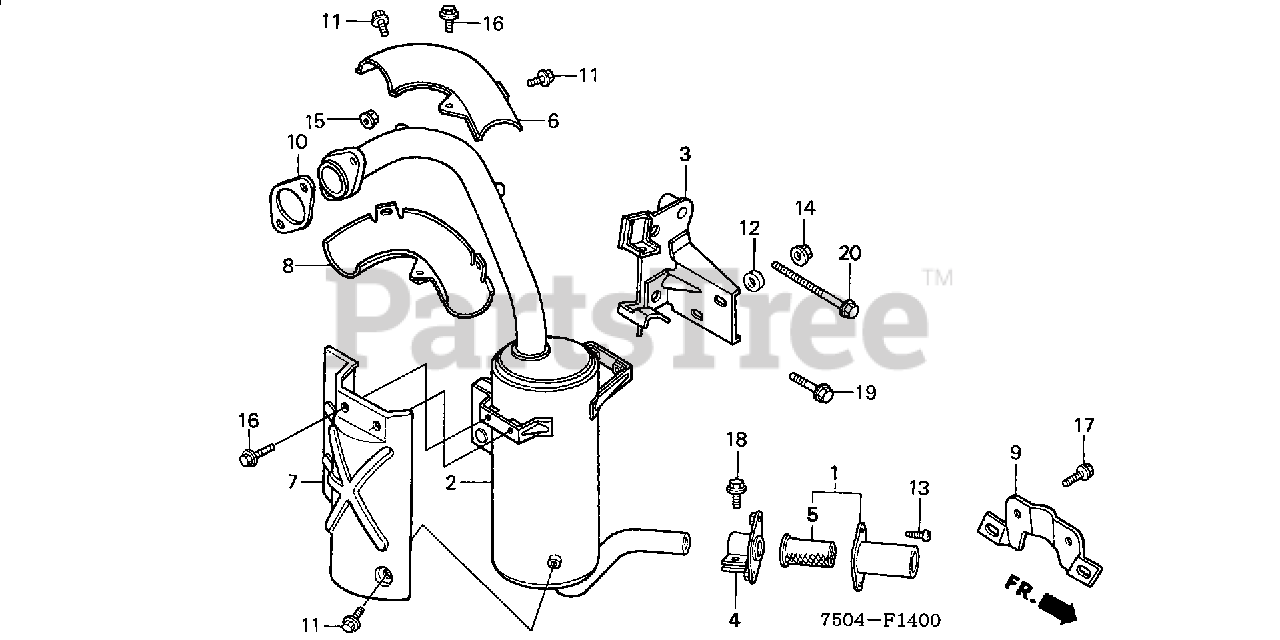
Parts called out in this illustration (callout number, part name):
1	CAP SET, ARRESTER
3	STAY, MUFFLER
4	CLAMP, ARRESTER BASE
5	ARRESTER, SPARK
6	PROTECTOR A, EX. PIPE
7	PROTECTOR, MUFFLER
8	PROTECTOR B, EX. PIPE
9	STAY, EX. PIPE
10	GASKET, MUFFLER
11	BOLT, FLANGE (6X8)
13	SCREW, PAN (5X8)
14	NUT, FLANGE (8MM)
15	NUT, FLANGE (8MM)
16	BOLT, FLANGE (6X12)
17	BOLT, FLANGE (8X14)
18	BOLT, FLANGE (8X16)
19	BOLT, FLANGE (8X20)
20	BOLT, FLANGE (8X68)
